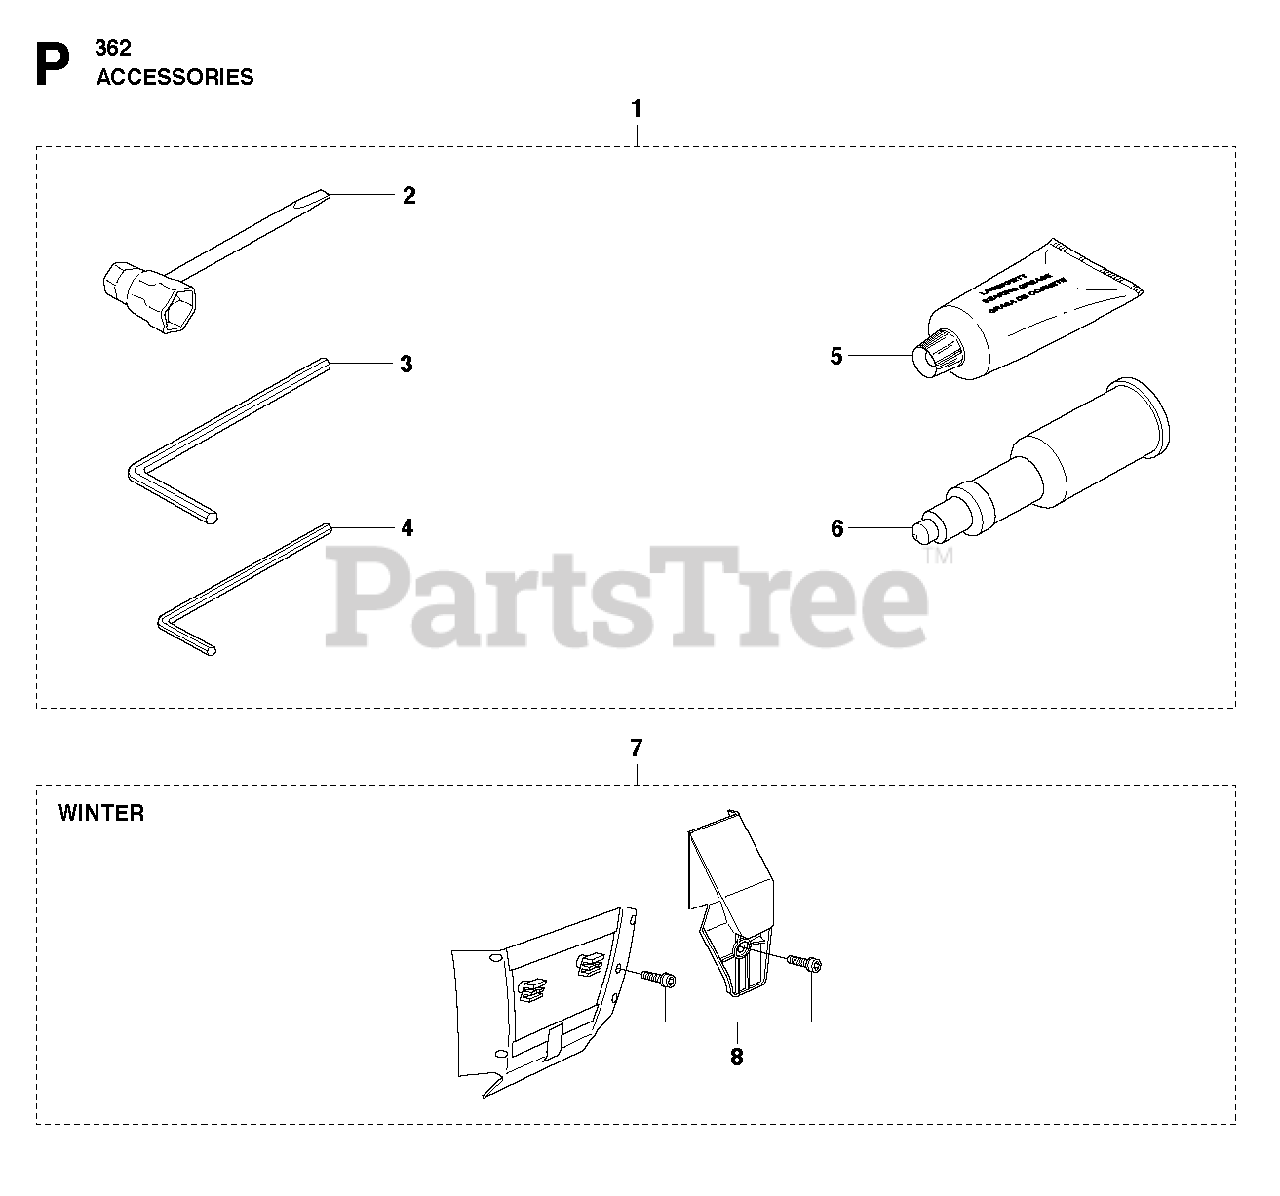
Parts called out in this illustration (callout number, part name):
1	TOOL KIT
2	COMBI TOOL
3	L-SPANNER
4	L-SPANNER
5	GREASE
6	Grease Gun
7	WINTER KIT
8	SCREW
